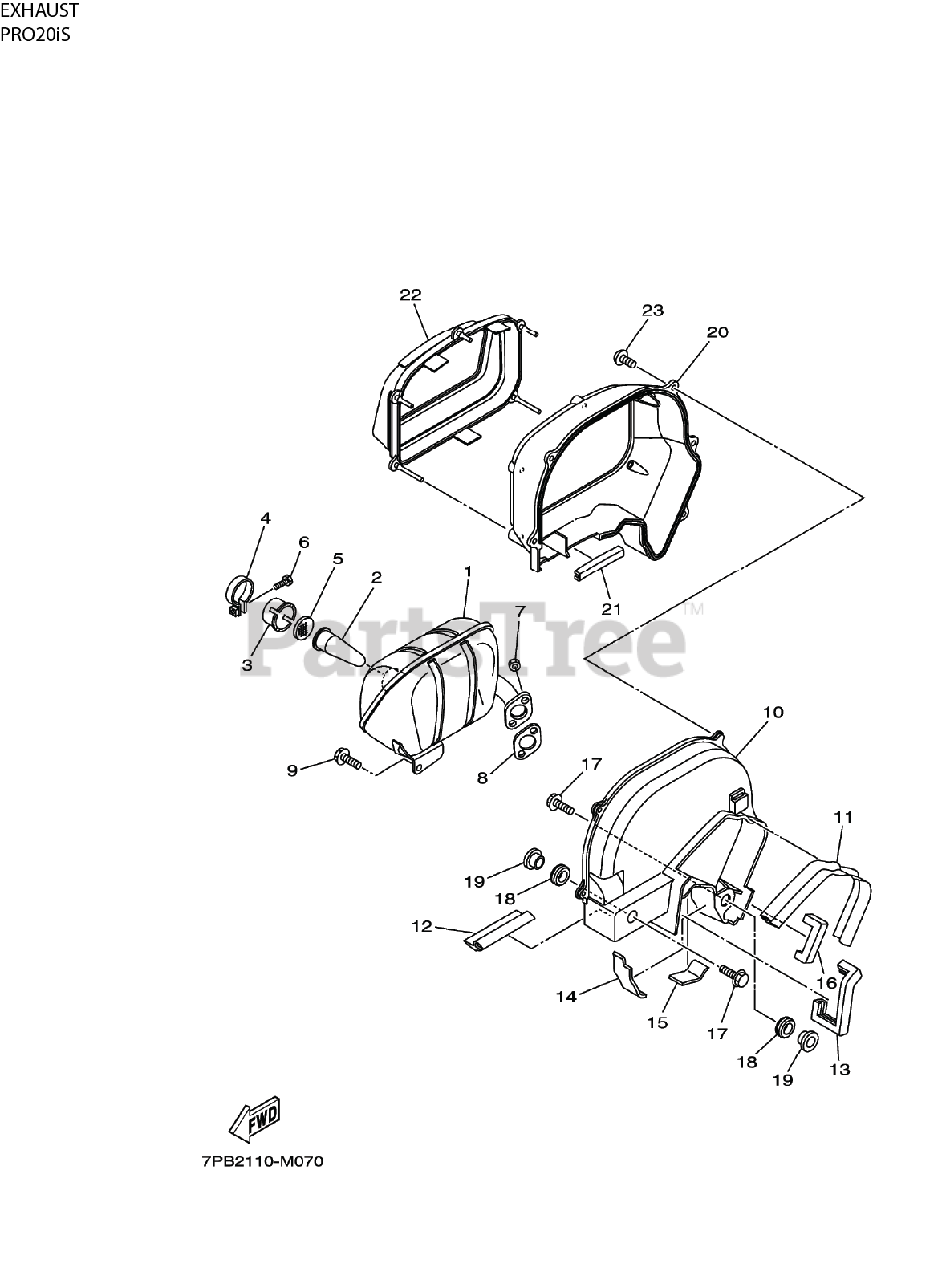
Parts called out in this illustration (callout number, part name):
1	MUFFLER 2
2	ARRESTER, SPARK
4	CLAMP - BAND, SILENCER
5	SCREEN - NET, WIRE
6	SCREW - HEXAGON
8	GASKET, EXHAUST PIPE
9	SCREW - BOLT FLANGE
10	GUARD, MUFFLER
13	SEAL, PROTECTOR
14	SEAL, PROTECTOR 2
15	SEAL, PROTECTOR
16	SEAL, PROTECTOR
17	SCREW - BOLT FLANGE
20	GUARD, MUFFLER ASSEMBLY
21	SEAL, PROTECTOR
23	SCREW - TRUSS HEAD TAPPING
